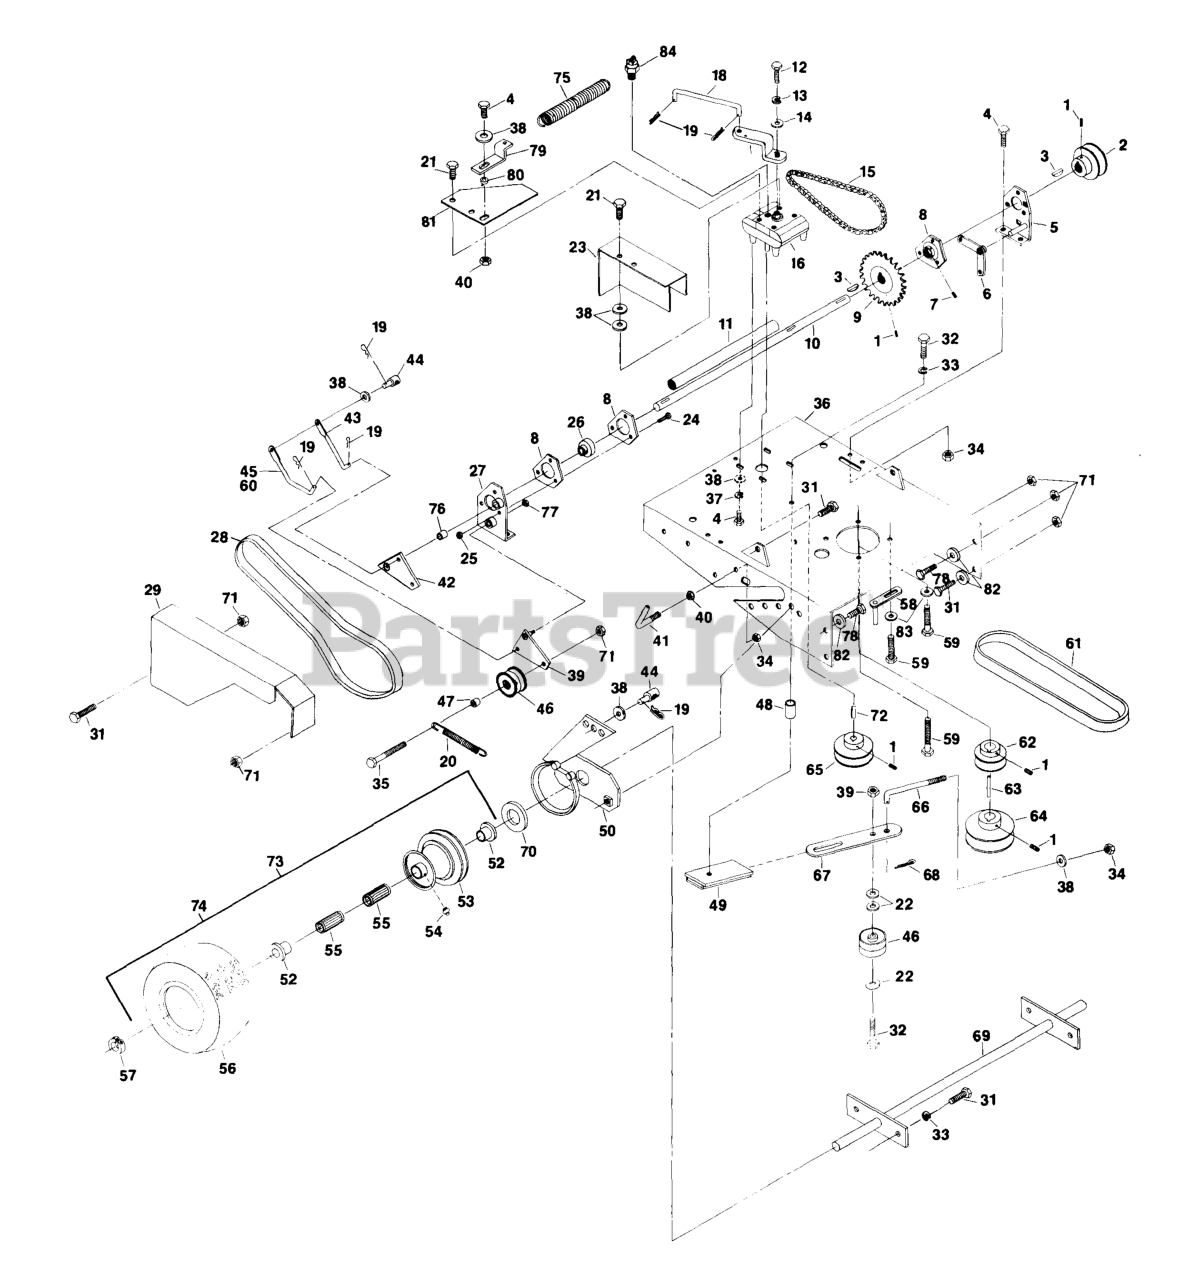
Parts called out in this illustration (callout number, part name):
1	SCREW-SET
6	BELLCRANK
13	WASHER-LOCK
15	DRIVE CHAIN
17	LEVER,TRANSMISSION
19	PIN-COTTER
20	SPRING-EXTENSION
28	BELT,COG
29	Fitting, Elbow
37	WASHER-LOCK
39	ARM - IDLER
42	ARM - IDLER
44	SWIVEL,SHORT ADJUSTING
45	LINKAGE,LOWER CALIPER RH
46	PULLEY,IDLER
55	BEARING,ROLLER WHEEL 32
55	BEARING,ROLLER
57	COLLAR,LOCKING 7/8
58	GUIDE - BELT, 32
61	BELT,TRANSMISSION
63	KEY,MACH 1/4X1/4X2-5/8
64	PULLEY,CAST IRON
66	TIGHTENING ARM
69	WLD,AXLE 32
77	NUTTORQUE ZKPLT
83	WASHER-SPRING
84	SWITCH-START, NEUTRAL
